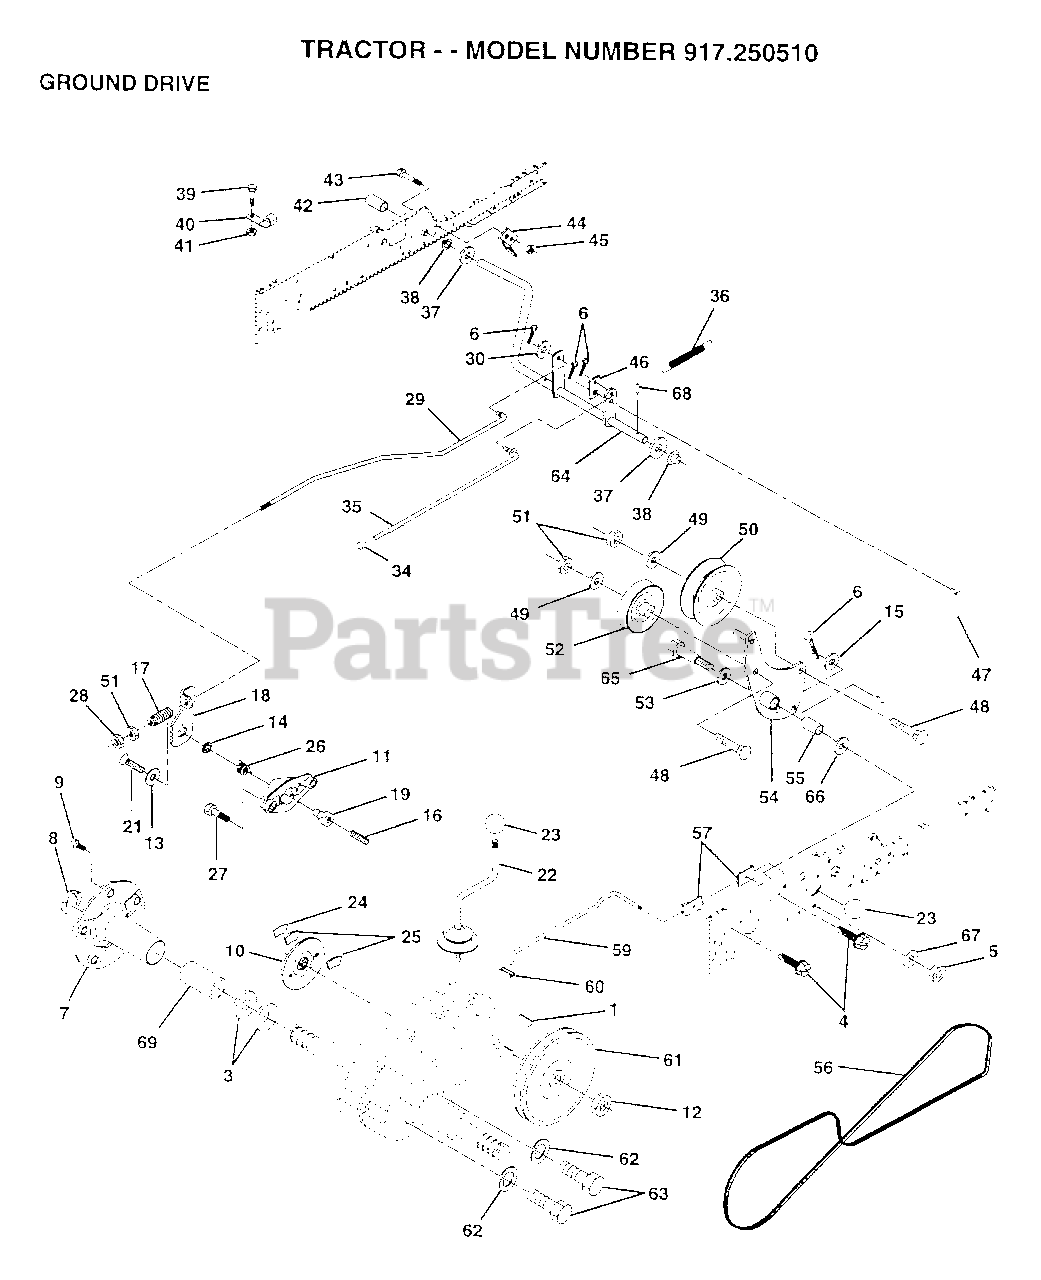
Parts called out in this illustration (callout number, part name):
3	WASHER T
4	SCREW LT
6	COTTER PIN
8	KLIP RING
9	BOLT.HUB.WHL.REAR
10	BRAKE.DISC.
11	YOKE BRAKE DISC
12	NUT STD
13	WASHER SPECIAL
14	BUSHING LEVER BKT
15	WASHER
16	SCREW SET 1/4-20
17	"SPRING,ROD BRAKE"
18	LEVER BRAKE GT
19	CAM BRAKE DISC GT
21	SCREW FLT 1/4X28
22	GEAR SHFT LVR T
23	KNOB T(3/8 HOLE)
24	SUPPORT PUCK BRKE
25	PUCK BRAKE TOP
26	SPRING RET BRAKE
27	SCREW HX WASH
28	NUT
29	ROD BRAKE ZINC GT
30	WASHER
35	ROD BRAKE PART GT
37	WASHER
38	NYLINER T
39	SCREW
40	ACT-SWITCH T
42	PEDAL COVER T
43	BOLT LT
44	BRKT SWITCH GT
45	NUT
46	RETAINER.SPRING
47	ROD.CLUTCH
48	BOLT
49	WASHER
50	FLAT IDLER PULLEY
51	NUT
52	PULLEY.IDLER.V.GR
53	WASHER T
54	ARM.ASM.IDLER.CLU
55	"LY, BEARING"
56	BELTV.GR.DR.83.
57	BRACKET.ROD.SHIFT
59	ROD SHIFT HI LO
60	CONNECTING LINK
62	LOCKWASHER
63	BOLT
65	AXLE BOLT
66	WASHER.HARD.BLADE
67	WASHER
68	ROLL PIN STD
69	"COVER, HUB"
